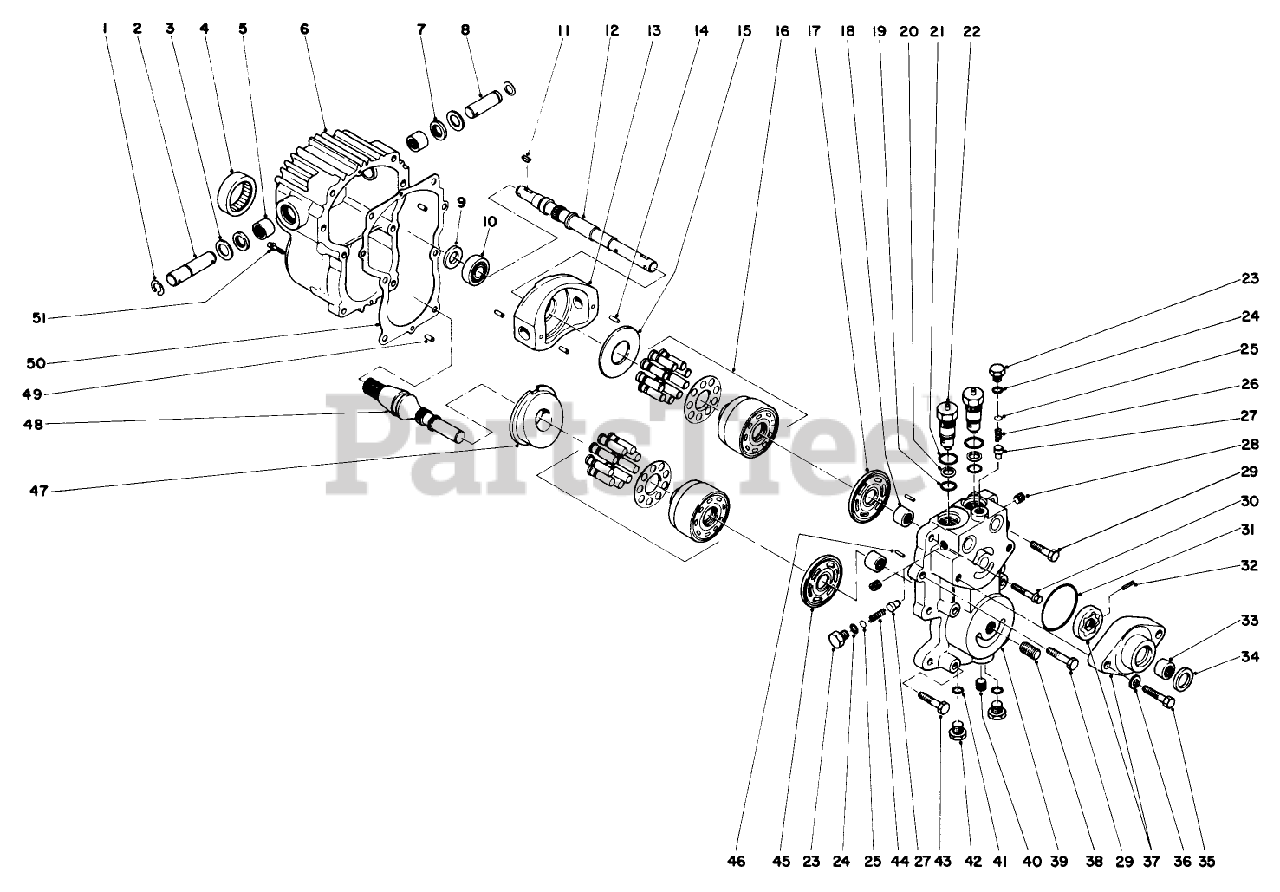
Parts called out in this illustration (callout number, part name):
1	RING-RETAINING
2	SHAFT-TRUNNION
3	WASHER-FLAT
4	BEARING-ROLLER
5	Bearing-Needle
6	Housing
7	SEAL-LIP
8	SHAFT-TRUNNION
9	Up Seal
10	BEARING-BALL
11	KEY-WOODRUFF
12	SHAFT-PUMP
13	Variable Swashplate
14	PIN-SPRING
15	THRUST PLATE
16	Cylinder Block Kit
17	PLATE-VALVE, PUMP
18	BEARING-NEEDLE
19	O-RING
20	RING-BACK UP
21	O-RING
22	Check Valve Assembly (Incl. Ref. #19-21)
23	PLUG-HH
24	O-RING
25	PACK-SHIM
26	SPRING
27	Cone-Charge Relief
28	PLUG-PIPE
29	SCREW-HH
30	CAPSCREW
31	O-RING
33	.625 NEEDLE BEARING
34	SEAL-LIP
35	SCREW-HH
36	WASHER
37	Charge Pump Kit (Incl. Ref. #31-34)
38	UNION-FILTER
39	Center Section
40	PIPE PLUG
41	"O" Ring
42	Threaded Plug (Incl. Ref. #41)
43	SCREW-HH
44	SPRING-VALVE
45	PLATE-VALVE, MOTOR
46	PIN-DOWEL
47	Swashplate
48	Motor Shaft
49	Pin
50	GASKET
51	12 Point Capscrew
